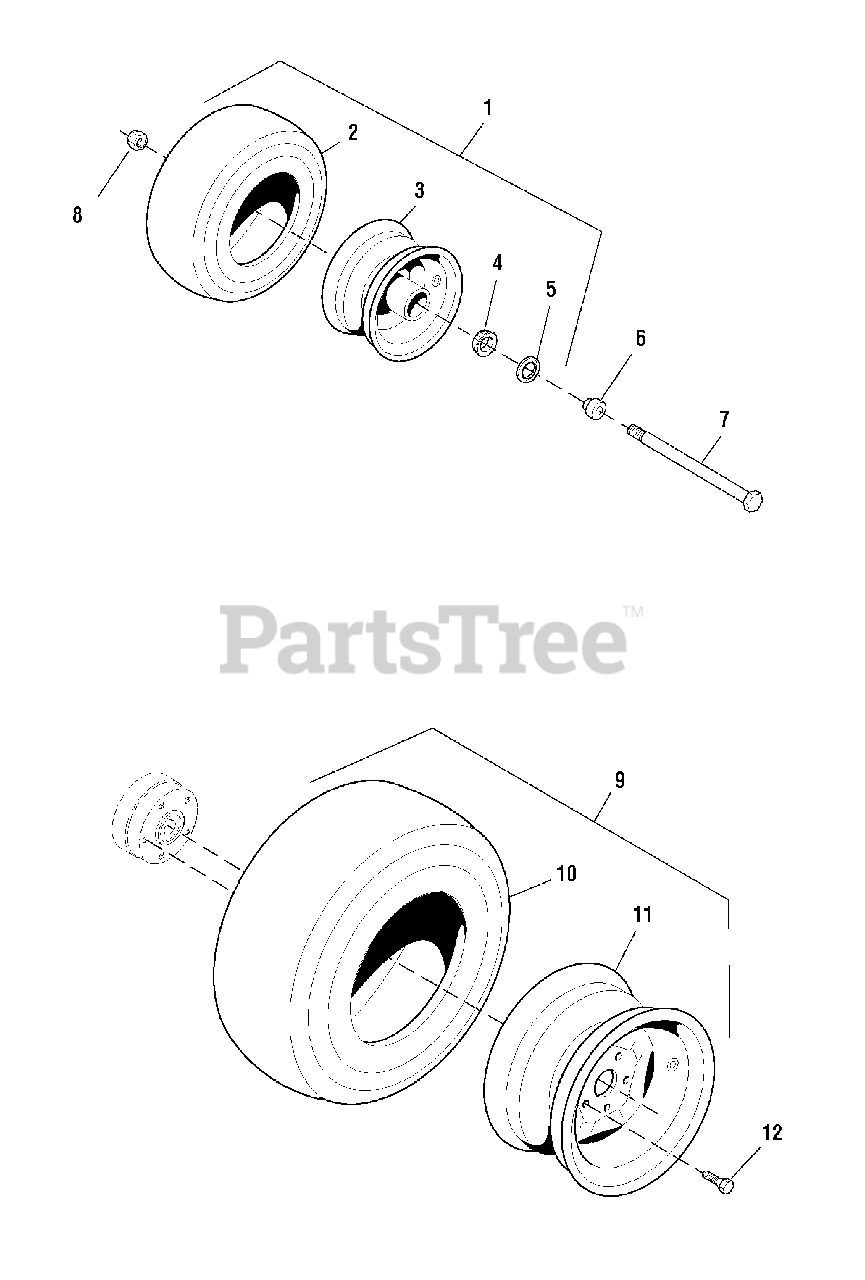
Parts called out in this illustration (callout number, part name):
1	WHEEL & TIRE ASSEMBLY, Front, 13 x 5.0 x 6, Complete
2	TIRE, Front, 13 x 5.0 x 6
3	WHEEL ASSEMBLY, Front, for 13 x 5.0 x 6 Tire, Complete
4	BEARING, TAPERED CONE
5	SEAL, GREASE
6	ADAPTER, Caster Wheel (2 per wheel)
7	CAPSCREW, Hex Hd, 1/2-13 x 7-1/2
8	NUT, Hex, Nylon Lock, 1/2-13
9	WHEEL & TIRE ASSEMBLY, Rear, 23 x 9.5 x 12, Complete (Includes Ref 10 & 11)
10	TIRE, Rear, 23 x 9.5 x 12
11	WHEEL ASSEMBLY, Rear, for 23 x 9.5 x 12 Tires
12	WHEEL LUG, 1/2 x 1-5/8
